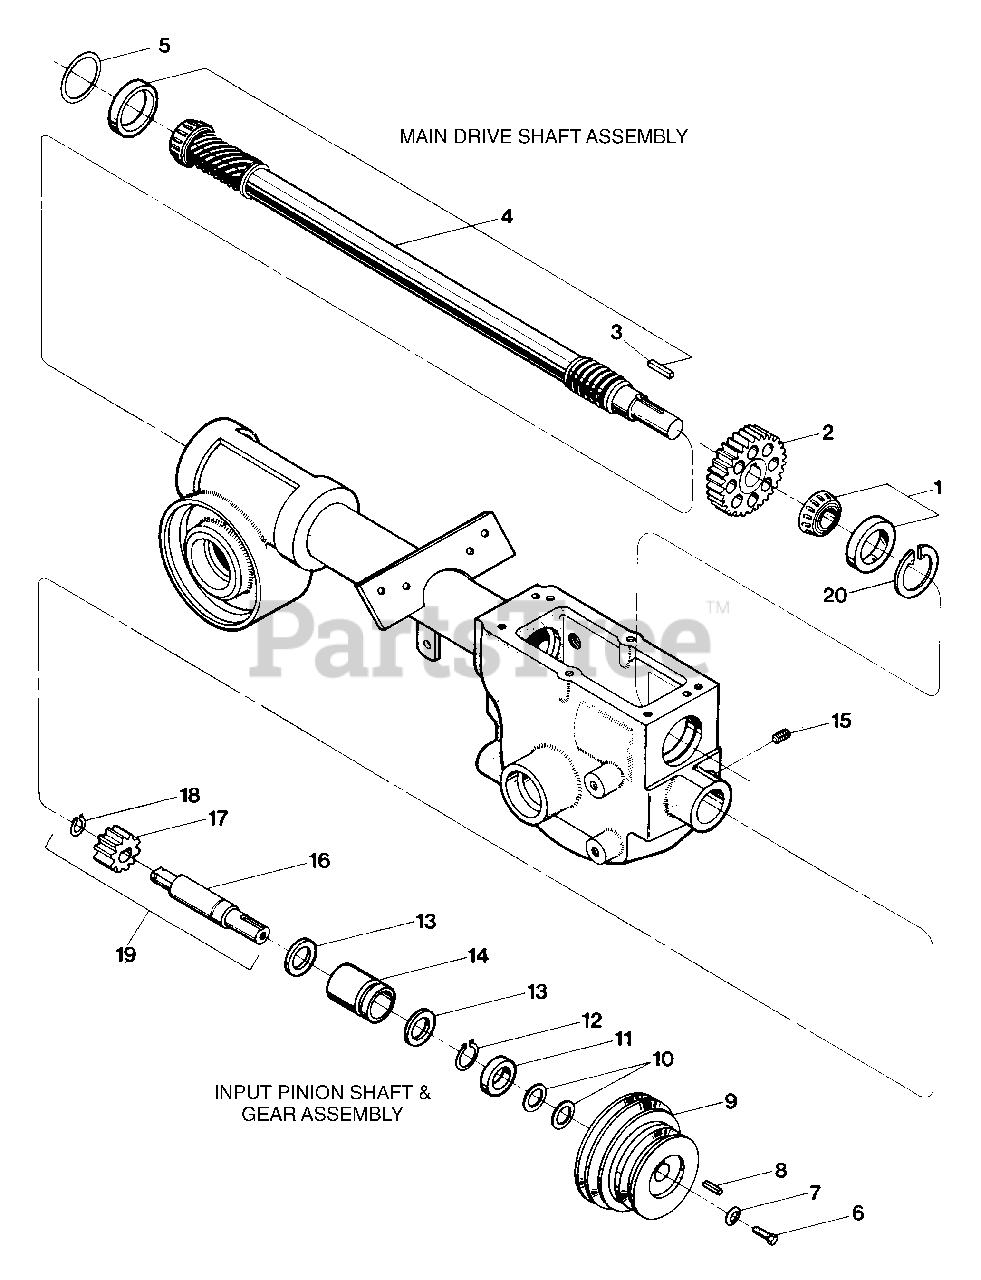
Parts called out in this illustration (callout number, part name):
1	Bearing, front, tapered roller, w/race
2	Gear, spur
3	Key, 3/16 sq. x 1
4	Drive shaft, main assembly
5	Shim, rear bearing cap, .010 thick
5	Shim, rear bearing cap, .030 thick
5	Shim, rear bearing cap, .005 thick
6	Screw, hex hd., 5/16-24 x 3/4, Grade 5
7	Washer, disc spring
8	Key, 3/16 sq. x 1
9	Pulley, trans. drive, 3 grooves
10	Washer, support
11	Oil seal, input pinion shaft
12	Ring, retaining, external
13	Washer, thrust
14	Bushing
15	Set screw, 5/16-18 x 3/8
16	Input pinion, steel shaft
17	Gear, input pinion
18	Retainer, snap ring, external
19	Pinion assembly
20	Retainer, snap ring, internal
